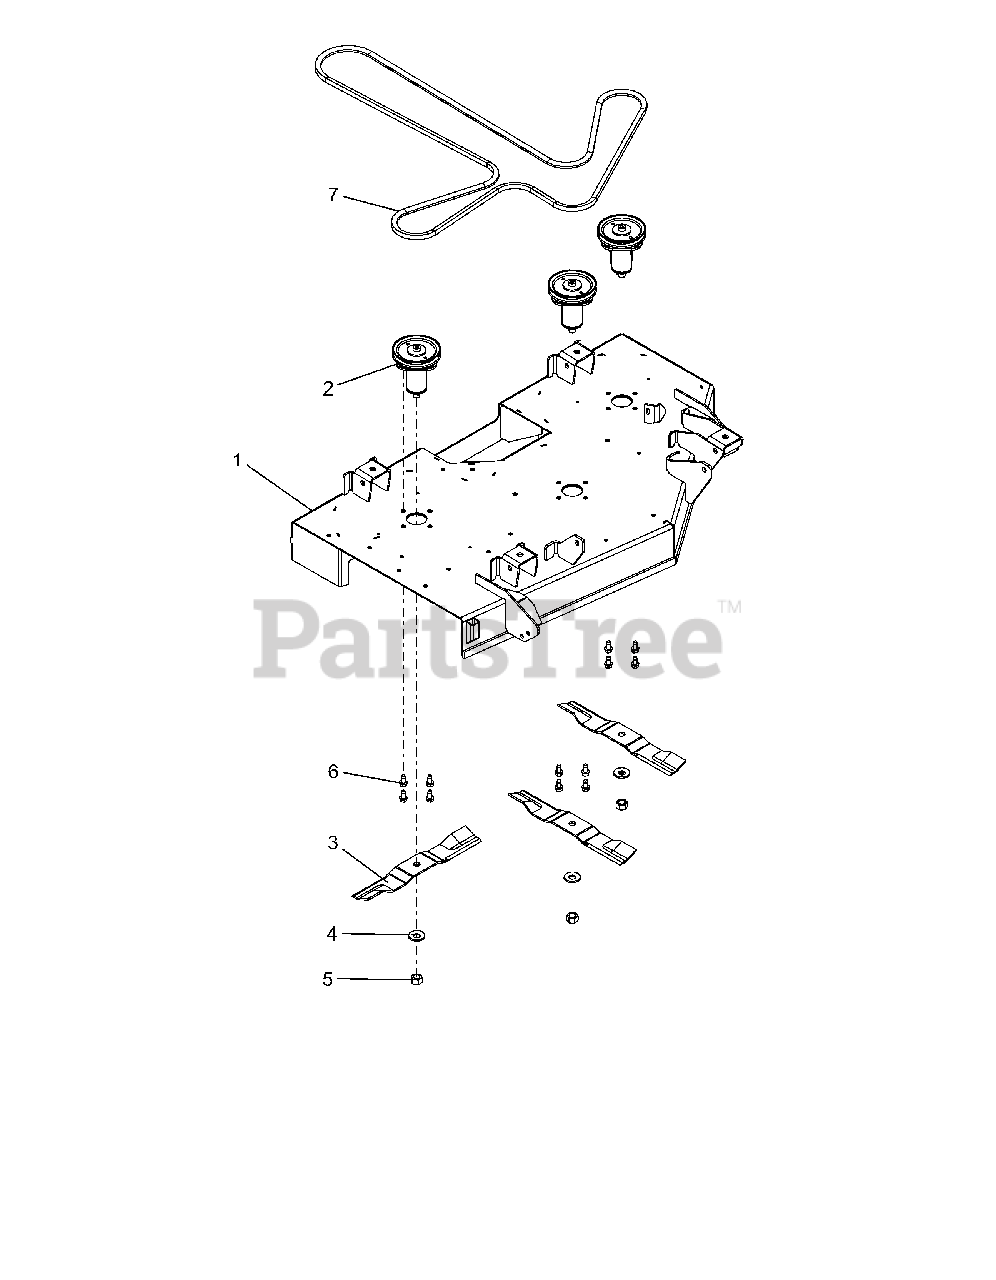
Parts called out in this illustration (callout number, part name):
1	KIT, 42" GRAVELY DECK W/DECALS
2	KIT, DECK SPINDLE ASM-IKON-ZTX
3	BLADE, MOWER 15.00"
4	WSHR-BLVL .669X1.535X.138
5	NUT-STD .625-18 ZCC
6	SCR,TAP .375-16X.75 HWH TR ZCC
7	V-BELT, 4L-WRAPPED
